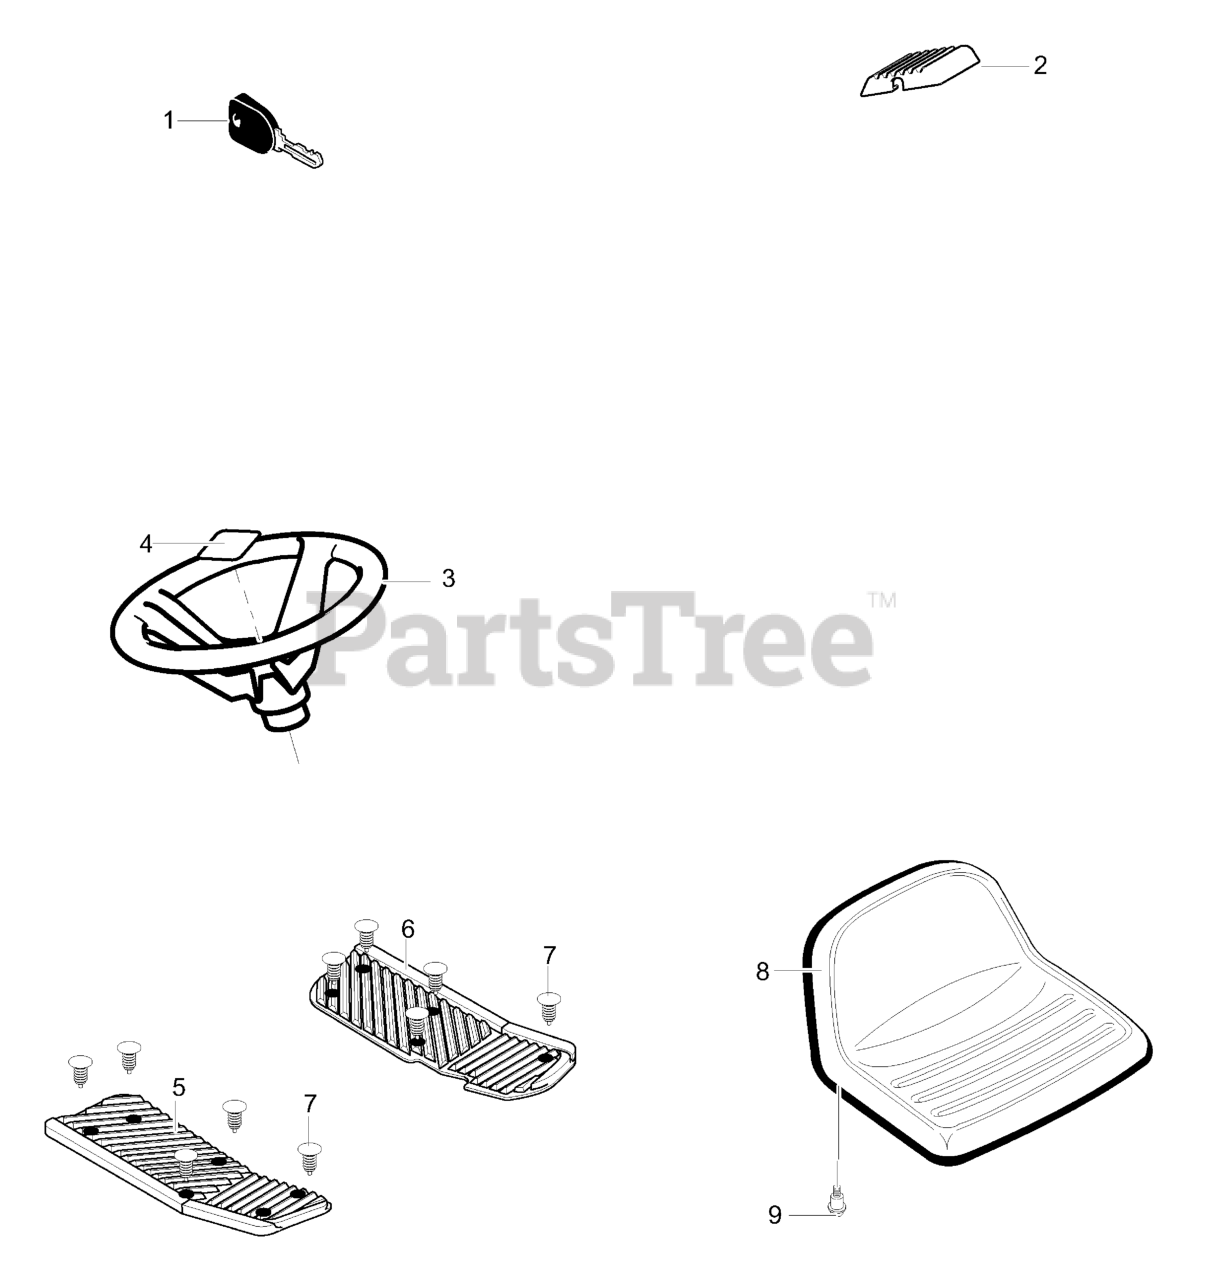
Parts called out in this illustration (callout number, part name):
1	IGNITION KEY
2	PAD, BRAKE/CLUTCH
3	STEERING WHEEL
4	INSERT, 4-SPOKE
5	PAD, RIGHT FOOTREST
6	PAD, LEFT FOOTREST
7	FASTENER, RATCHET
